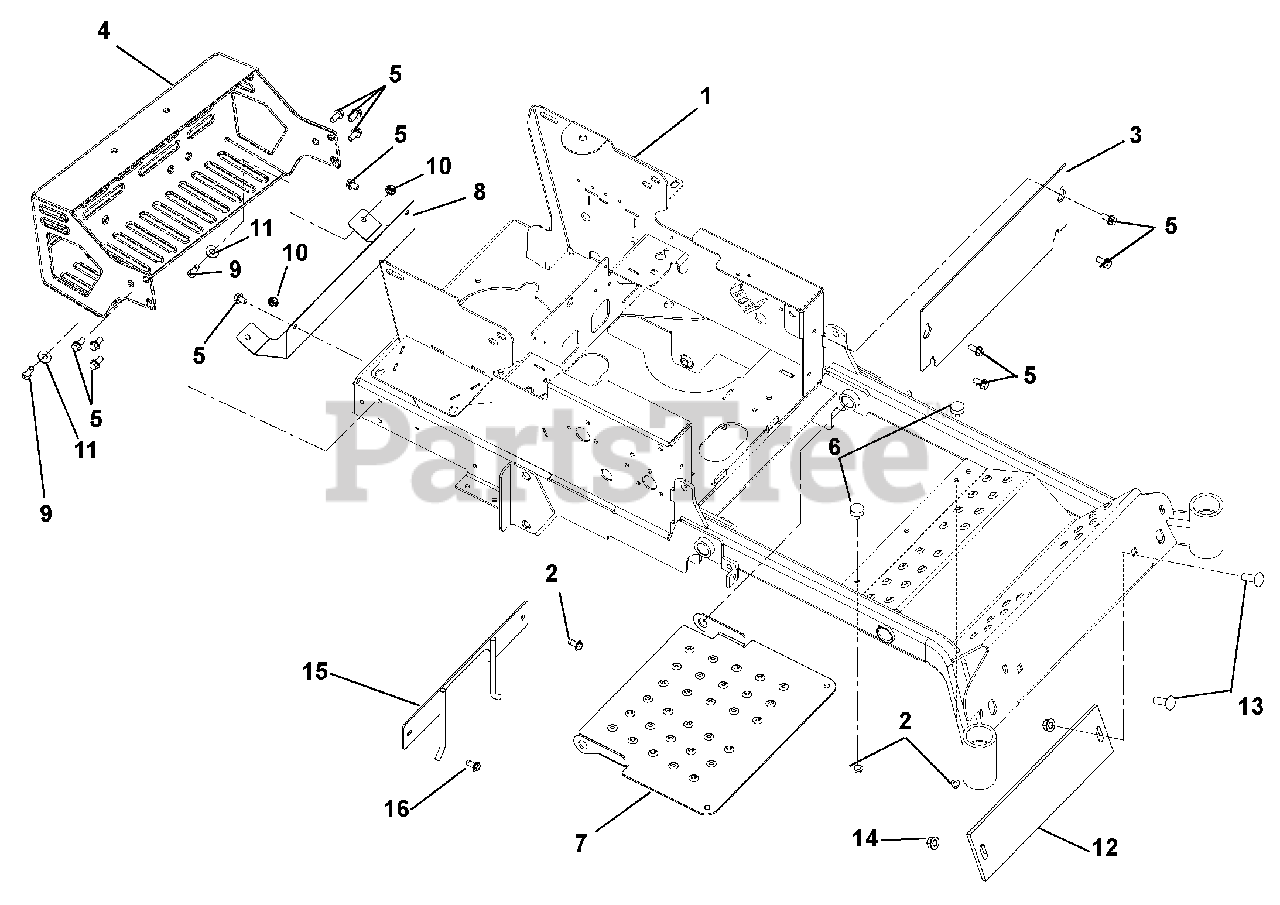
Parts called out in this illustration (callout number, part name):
1	Weldment, 44" – 48" HD Frame (991090, 082)
1	Weldment, 52" – 60" HD Frame (991083, 084, 091)
2	Nut, Spin Lock Flange .312-18
3	Kick Plate
4	Bumper, Gravely HD
5	Screw, Tapping .38-16 x .75 Hex Washer Head
6	Bumper, Rubber
7	Panel, Inspection
8	Heat Shield
9	Bolt, Hex .38-16 x 1.00 Grade 5
10	Nut, Nyloc Flange .38-16
11	Washer, Flat Steel .438 x 1.00 x .083
12	Counterweight CZ Front (991090, 082)
13	Bolt, Round Head Square Neck .50-13 x 2.25 Grade 5
14	Nut .50-13 Nyloc Flange
15	Weldment, PTO Belt Finger
16	Screw, Tapping .38-16 x .75 Hex Washer Head Thread
